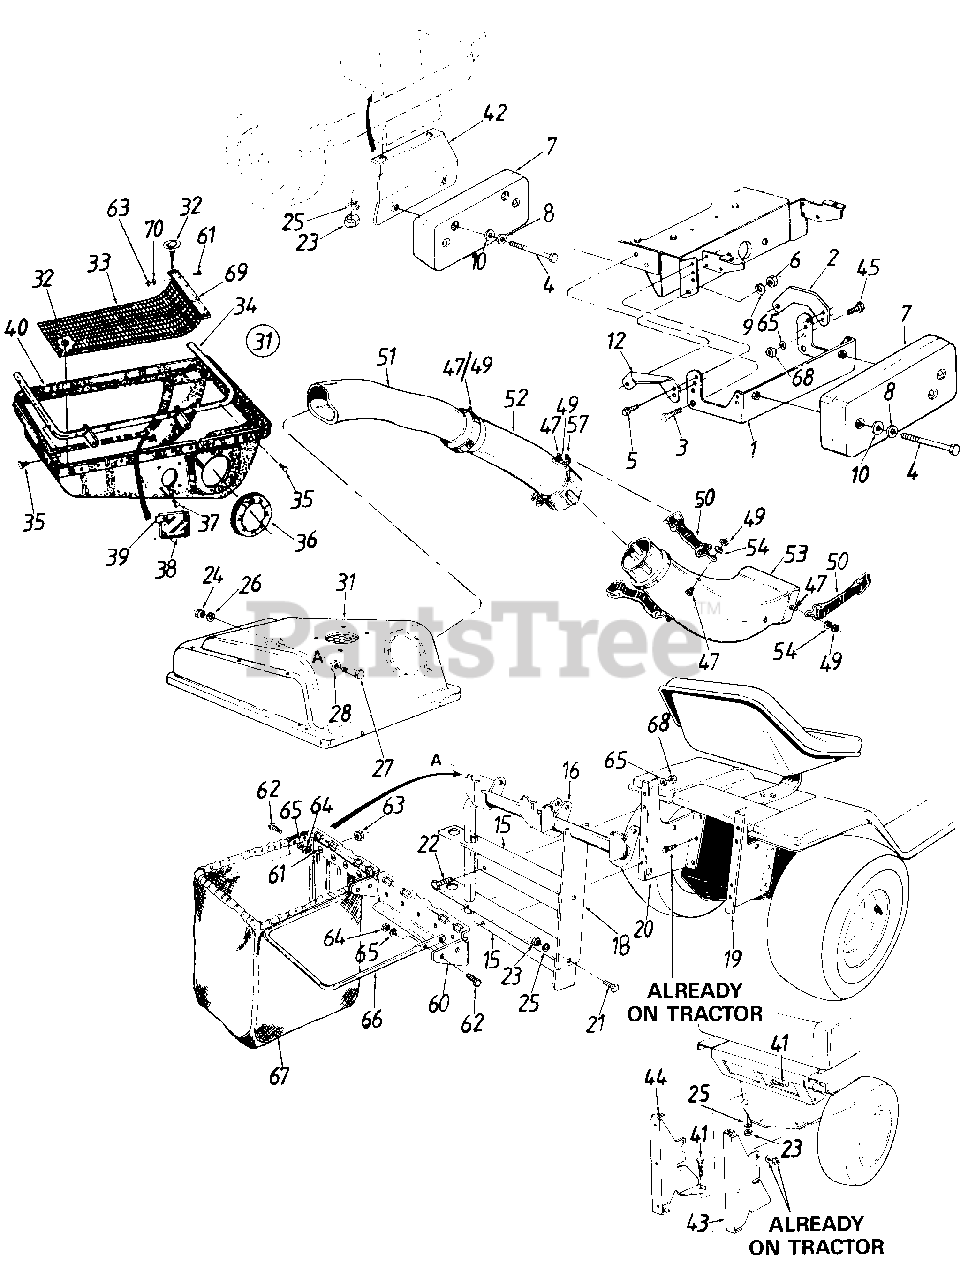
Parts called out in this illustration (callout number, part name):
1	Weight Brkt. Ass'y.
2	Weight Brkt. Tie Strap L.H.
3	Hex Bolt 7/16-20 x 1.0" Lg.*
4	Hex Bolt 3/8-16 x 4.5" Lg.
5	Hex AB Tap Scr. 5/16-18 x 1.0"
6	Hex Jam Nut 7/16-20 Thd.
7	Front Counter Weight 38 lbs.
8	Bell.-Wash. 400" I.D. x .88" O.D.
9	L.-Wash. 7/16" I.D.
10	Fl.-Wash. .390" I.D. x 1.12" O.D.
12	Weight Brkt. Tie Strap R.H.
15	Catcher Support Tube Mtg. Brkt.
16	Catcher Support Tube Ass'y
18	Catcher Latch and Support Brkt
19	Grass Catcher Support Brkt. R.H.
20	Grass Catcher Support Brkt. L.H.
21	Hex Bolt 5/16-18 x .75" Lg.
22	Hex Bolt 1/4-20 x .62" Lg. Grade 5
23	Hex Nut 5/16-18 Thd.
24	Hex Nut 3/8-16 Thd.
25	L.-Wash. 5/16" I.D.
26	L.-Wash. 3/8" I.D.
27	Shld. Bolt 3/8-16 x . 500" Dia.
28	Bell.-Wash. .505" .D. x 1.00" O.D.
31	Grass Catcher Cover Ass'y.
32	Twist Fastener
33	Screen
35	Hex Tap Scr. 1/4-20 x .5" N Lg.
36	Seal
37	Truss Mach. B-Tap Scr. #10 x .5" Lg.
38	Plastic Plate
39	Speed Nut
40	Grass Catcher Cover
41	Hex Bolt 5/16-18 x 1.0" Lg.
42	Counterweight Support Brkt.
43	Grass Catcher Support Brkt. R.H.
44	Grass Catcher Support Brkt-L.H.
45	Hex Bolt 1/4-20 x .88" Lg.
47	Hex Bolt 1/4-20 x .50" Lg.
49	Hex Ins. L.-Nut 1/4-20 Thd.
50	Retainer Strap Ass'y.
51	Catcher Elbow
52	Catcher Tube
53	Discharge Chute
54	L.-Wash. .270" I.D. x .57" O.D.
57	Retainer Hook Brkt.
61	Truss Mach. Scr. #10-24 x .50" Lg.
62	Hex Bolt 1/4-28 x .75" Lg.
63	Hex Sems Nut #10-24 Thd.
64	Hex Nut 1/4-28 Thd.
65	L.-Wash. 1/4" I.D.
67	Grass Catcher Bag
68	Hex Nut 1/4-20 Thd.
69	Screen Mtg. Brkt.
70	Flat Wash. 1/4" I.D.
